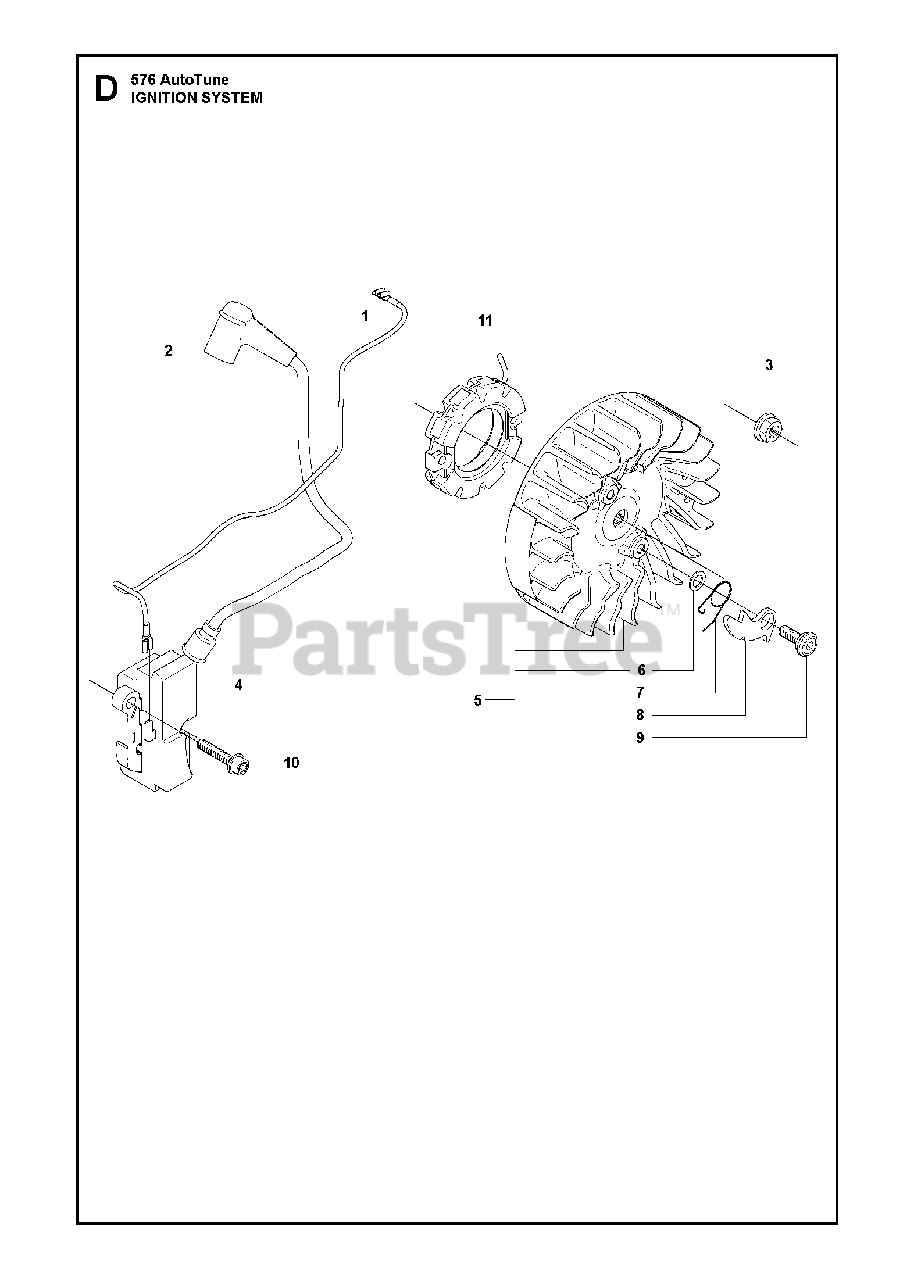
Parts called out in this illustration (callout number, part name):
1	SHORTING LEAD
2	SPARK PLUG CONN. KIT
3	NUT W/ WASHER
4	IGNITION MODULE
6	WASHER
7	SPRING
8	PAWL
9	SCREW M5X14
11	GENERATOR
